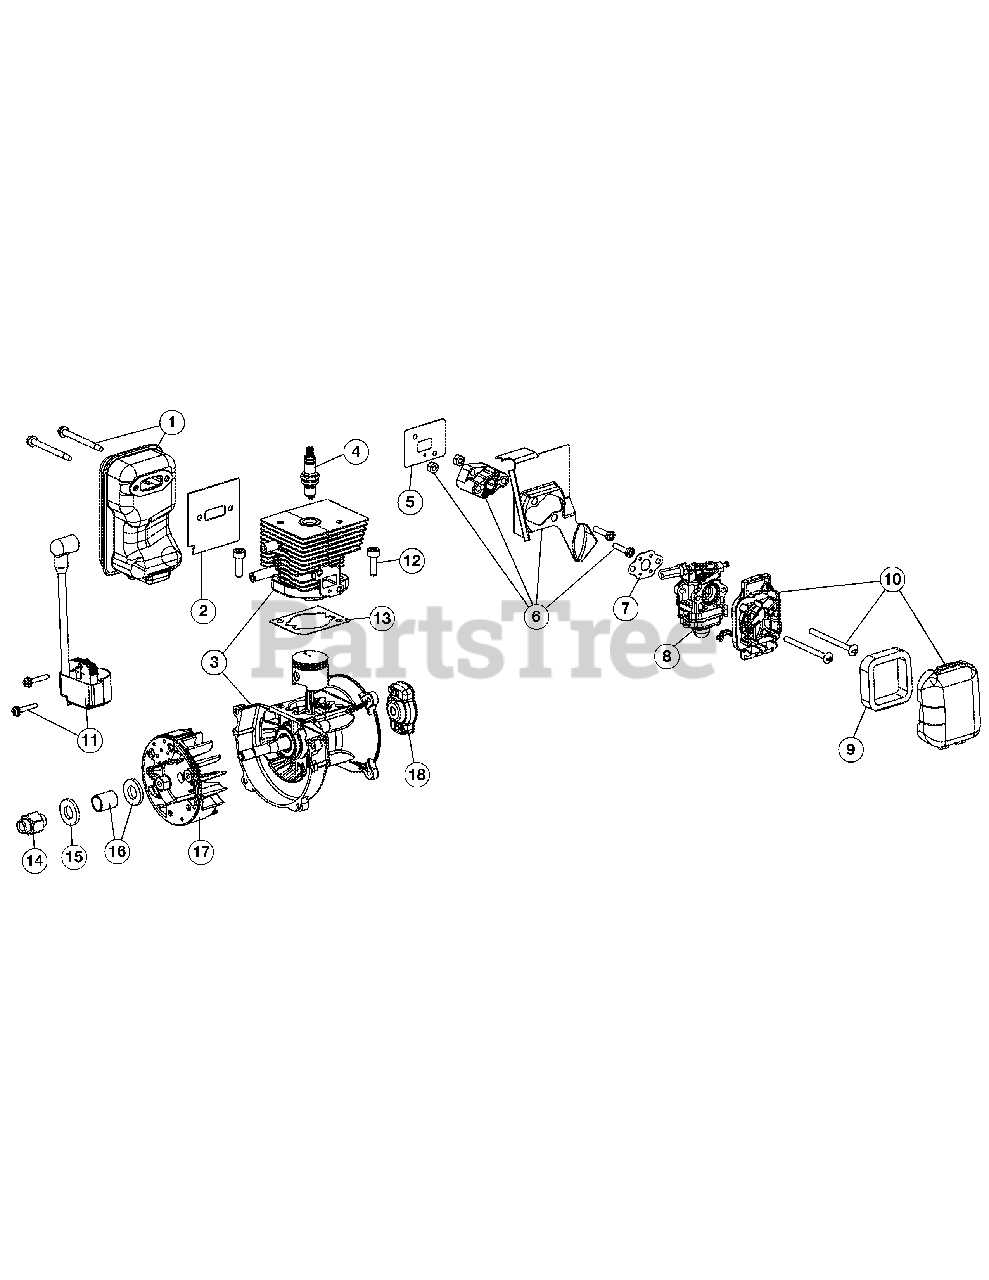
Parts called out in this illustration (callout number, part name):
1	Muffler Assembly
2	Muffler Gasket
3	Shortblock Assembly
4	Spark Plug
5	Insulator Gasket
6	Insulator Assembly
7	Carburetor Gasket
8	Carburetor Assembly
9	Air Filter
10	Aircleaner Assembly
11	Module Assembly
12	Screw
13	Cylinder Gasket
14	Flywheel Adapter
15	Washer
16	Bushing
17	Flywheel Assembly
18	Pawl Assembly
